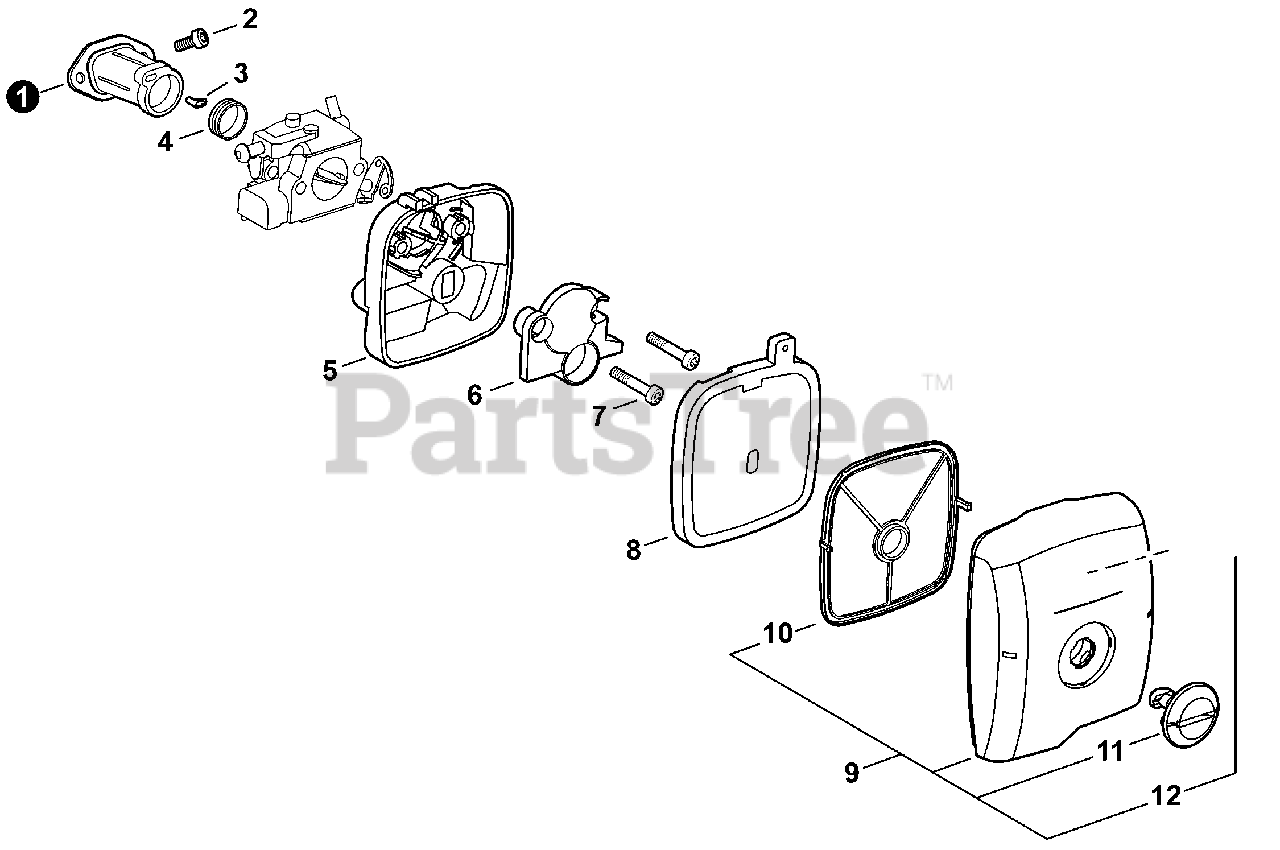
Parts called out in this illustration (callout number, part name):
1	BELLOWS, INTAKE
2	BOLT, TORX 5×12
3	COLLAR Ø3.2×6.5
4	SPRING, TENSION
5	CASE, AIR FILTER
6	PLATE, PREVENT
7	BOLT, TORX 5×50
8	FILTER, AIR
9	COVER ASSY, AIR FILTER
10	SEAL, AIR FILTER
11	KNOB, AIR FILTER COVER
12	LABEL, MODEL
